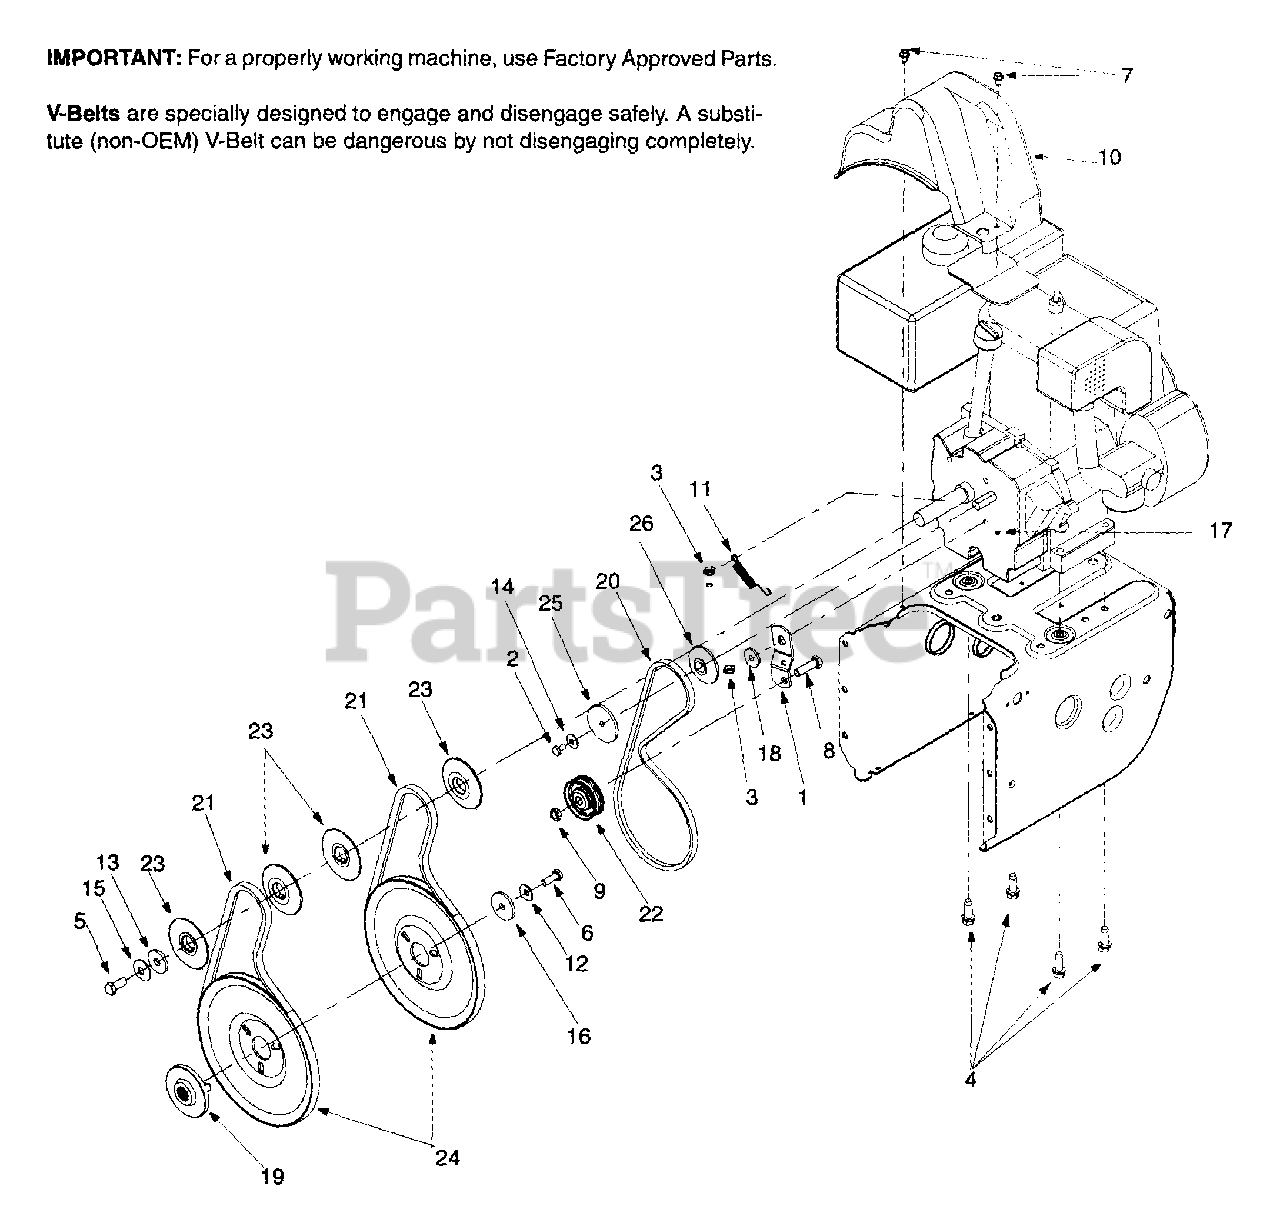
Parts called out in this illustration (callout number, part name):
3	Hex Screw w/ patch: 5/16-24 x 0.75"
4	Hex Washer Head TT Sems Screw
5	Hex Bolt 3/8-24 x .875" Gr.8
6	Hex Screw w/ Patch: 5/16-24 x .875" Gr.5
7	Hex Washer Head TT
8	Hex Screw: 3/8-16 x 1.0"
9	Top Lock Jam Nut: 3/8-16
10	Belt Cover
11	Extension Spring
12	Belleville Washer
13	Flat Washer
14	Bell Washer
15	Bell Washer
16	Flat Washer
17	Grease
18	Shoulder Spacer
19	Adapter Pulley
20	V-Belt
21	Belt
22	Flat Idler
23	Pulley Half
24	Auger Pulley
25	Pulley Half
26	Pulley Half
